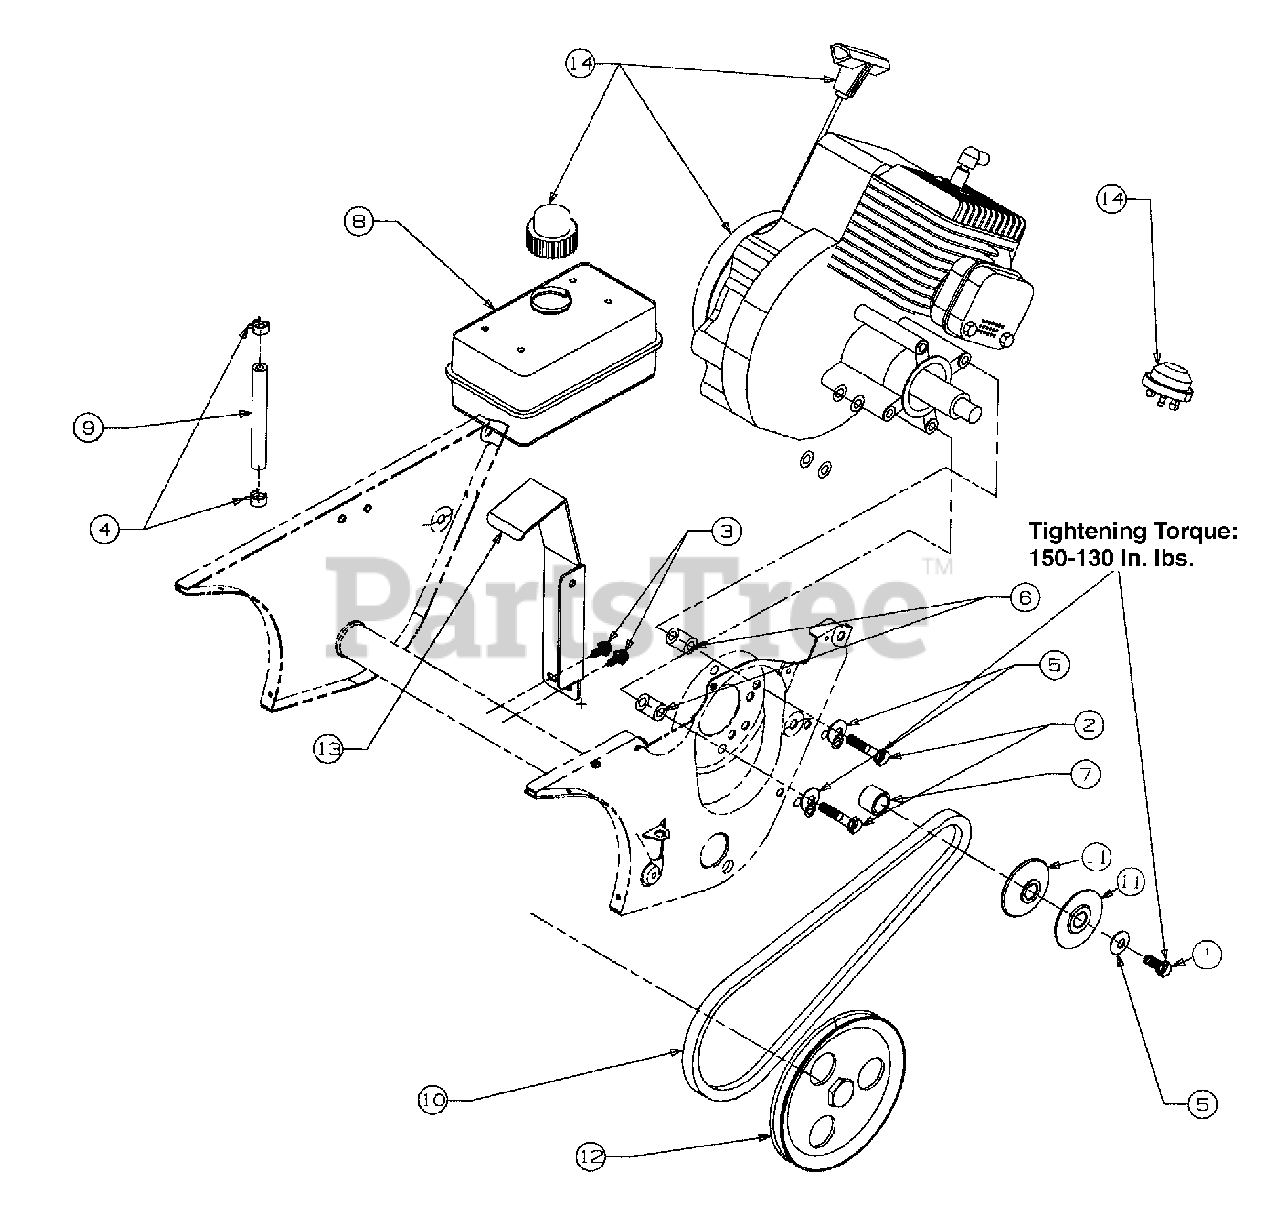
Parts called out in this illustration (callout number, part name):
1	Hex Cap Screw
2	Hex Cap Screw
3	Washer Screw
4	Hose Clamp
5	Bell Washer
6	Spacer
7	Spacer
8	Fuel Tank
9	Hose, Fuel - 12"
10	V-Belt
11	V-Pulley Half
12	Pulley
